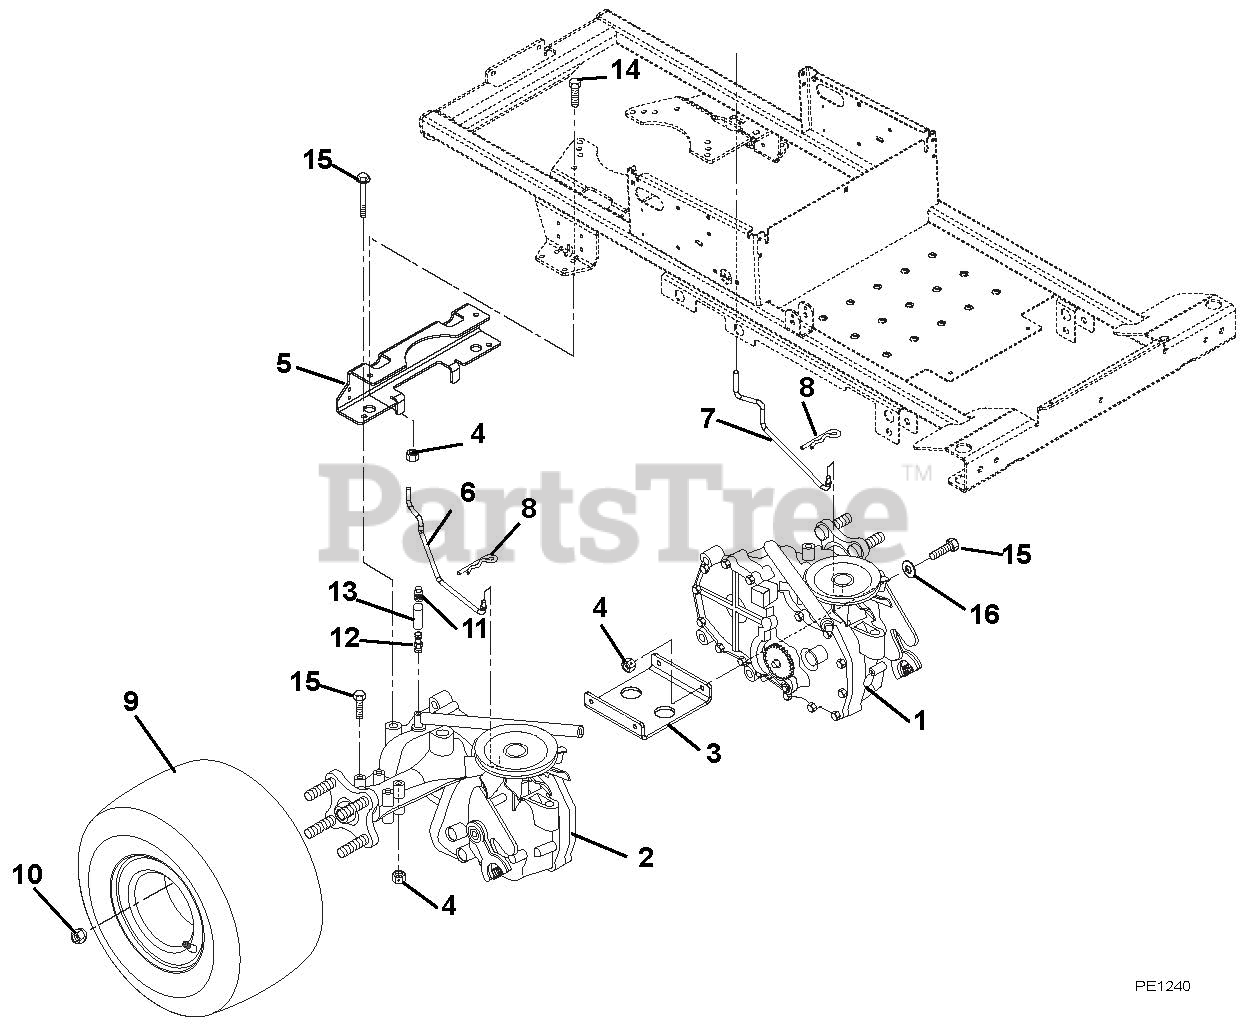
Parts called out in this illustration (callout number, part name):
1	EZT, Left Hand Transaxle
2	EZT, Right Hand Transaxle
3	Support, Transaxle
4	Nut 5/16-18 Flange Nyloc
5	Bracket, Clutch Stop
6	Rod, Dump RH
7	Rod, Dump LH
8	Pin, Hair .08 x.18 x 1.18
9	Assembly, Tire 8.5 x 18 2 Ply
9	Assembly, Tire 18 x 6.50-8 2 Ply
10	Nut, Lug .50-20
11	Cap, Vent .50
12	Fitting, Straight .50
13	Hose, Vent
14	Bolt, Hex .31-18 x 1.00
15	Bolt, Hex .31-18 x 2.75
16	Washer, Flat Steel .328 x .87 x .179
